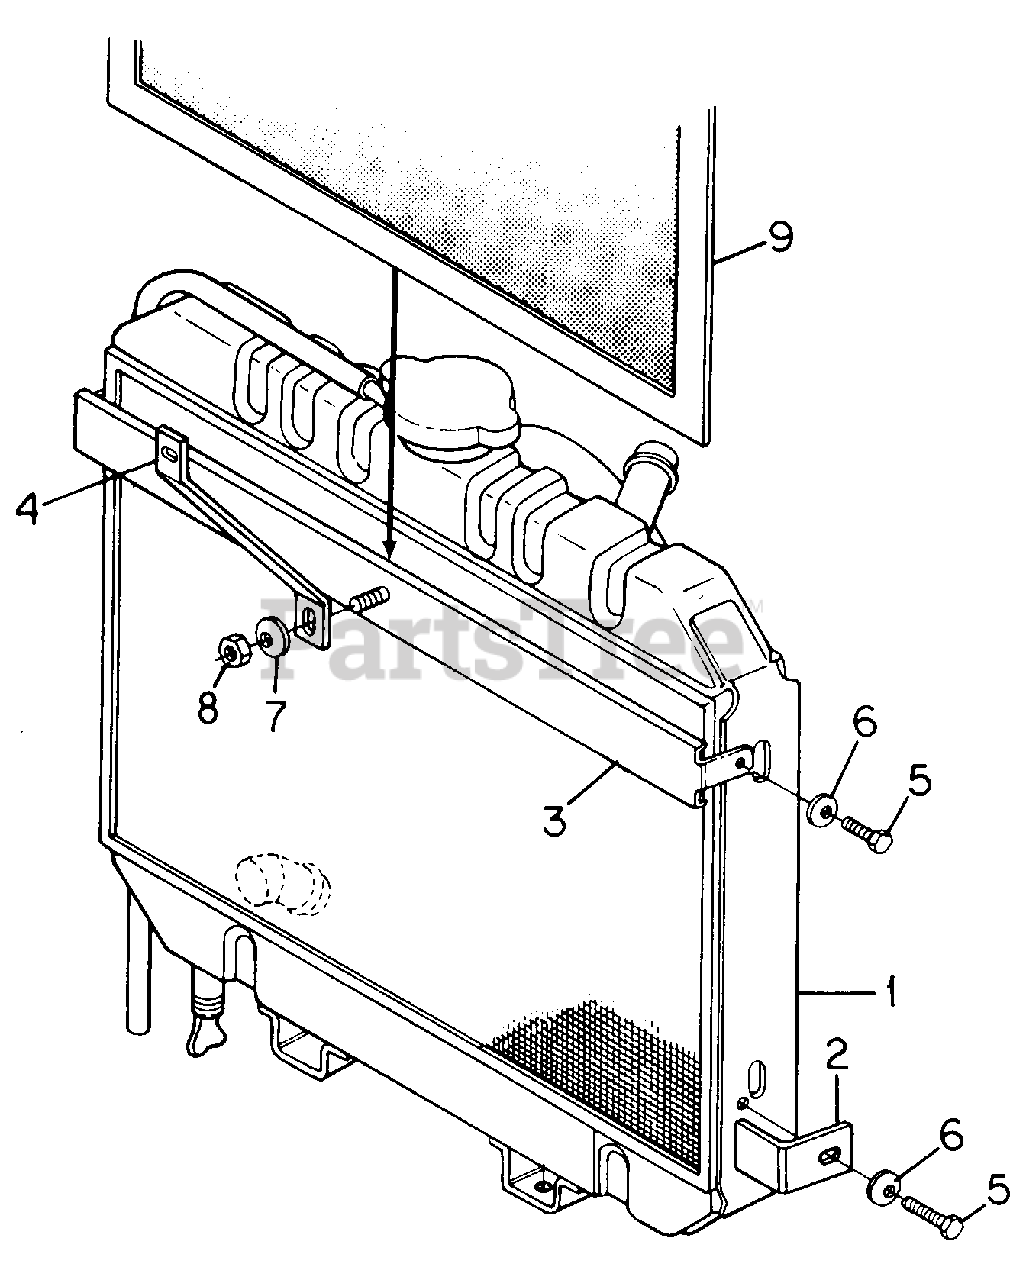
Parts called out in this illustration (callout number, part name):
1	Radiator Assy
2	Support, Screen
3	Brace, Radiator
5	Bolt, M6 X 14MM Class 8.8
6	Washer, Bell
7	Washer, Bell
8	Nut, 5/16 Cad P/T Lock Type 5
9	Screen, Radiator
